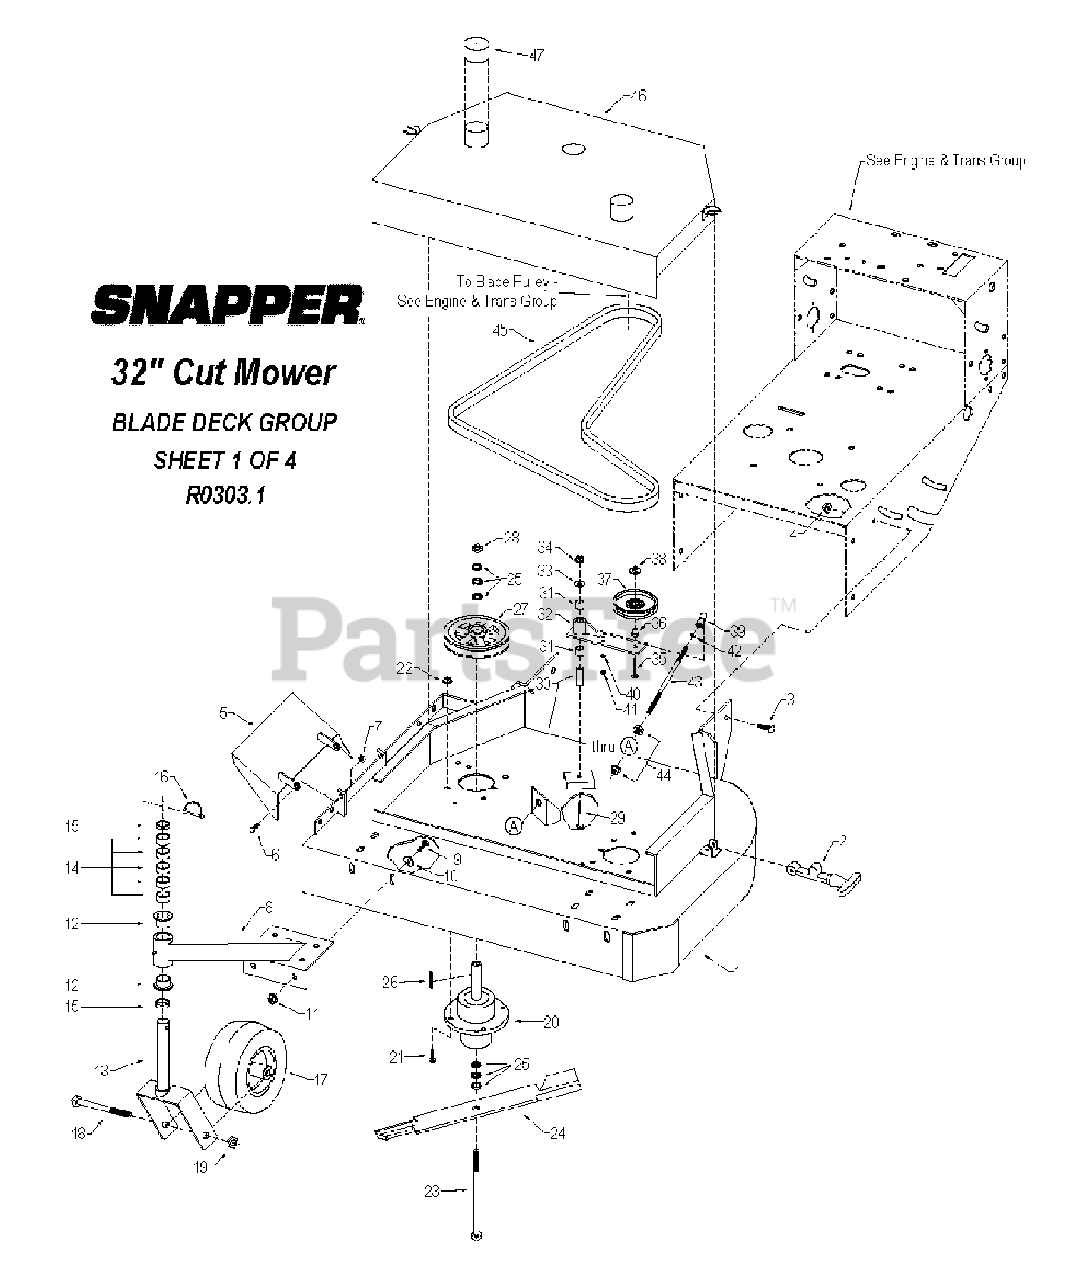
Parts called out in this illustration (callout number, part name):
1	Blade deck
2	Rubber hood strap (w/attaching hardware)
3	3/8-16 x 1" hex bolt
4	3/8-16 small serrated flange nut
5	Discharge deflector
6	5/16-18 x 3/4" hex bolt
7	5/16-18 lock nut
8	Caster arm
9	3/8-16 x 1" hex bolt
10	3/8" flat washer
11	3/8-16 small serrated flange nut
12	1" flange bushing
13	Caster horn
14	Caster height spacer - 1/2"
15	Caster height spacer - 1/4"
16	Lynch pin
17	9-3.50 x 4 wheel & tire assy
18	5/8-11 x 5" hex bolt
19	5/8-11 jam lock nut
20	Spindle assy
21	3/8-16 x 1" hex bolt
22	3/8-16 small serrated flange nut
23	5/8-11 x 9-1/2" hex bolt
24	16" lo-lift blade
25	1/4" spacer
26	Spindle shaft key - 1/4" x 1"
27	Blade belt pulley
28	5/8-11 jam nut
29	3/8-16 x 2-1/2" hex bolt
30	Deck idler arm pivot boss
31	3/4" sleeve bushing
32	Deck idler arm
33	1/2" flat washer
34	3/8-16 small serrated flange nut
35	3/8-16 x 2" carriage bolt
36	3/4" spacer bushing
37	Deck idler pulley
38	3/8-16 large serrated flange nut
39	3/8" ball joint - right hand thread
40	3/8 lock washer
41	3/8-24 jam nut
42	3/8-24 jam nut
43	Deck idler tension rod
44	3/8-16 small serrated flange nut
45	Blade belt
46	Deck hood
47	2" rubber hood cap
